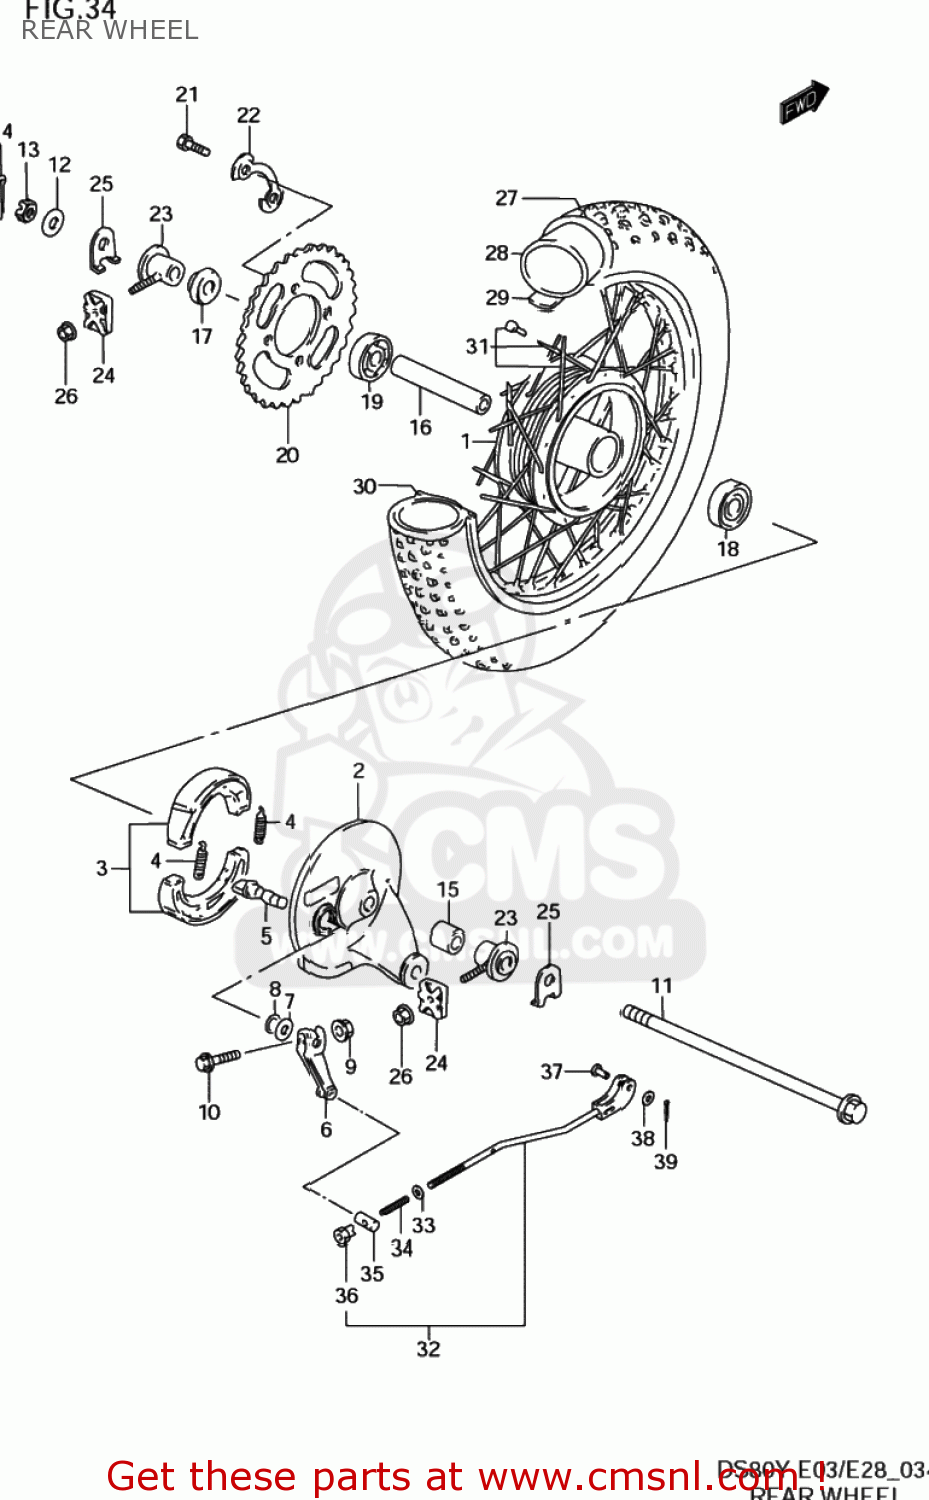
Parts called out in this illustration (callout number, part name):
1	HUB,RR
2	PANEL,RR BRAKE ANCHOR
3	SHOE SET,BRAKE (NAS)
4	SPRING(L:35.8)
5	CAM,BRAKE
6	LEVER,RR BRAKE CAM
7	WASHER(14.5X22X1.6)
8	O RING(D:2.5,ID:13.8)
9	NUT
10	BOLT
11	AXLE,RR
12	WASHER
13	NUT,M12X1.25X1
14	COTTER PIN
15	SPACER(12.1X22X22)
16	SPACER(12.6X19X91)
17	SPACER,RR AXLE,L
18	BEARING
19	BEARING
20	SPROCKET,RR(NT:34)
21	BOLT(8X25)
22	WASHER
23	ADJUSTER,CHAIN
24	PLATE,CHAIN ADJUSTER GUIDE
25	WASHER,CHAIN ADJUSTER
26	NUT
27	TIRE(3.00 12)
28	TUBE,INNER
29	PROTECTOR,INNER TUBE
30	RIM,RR WHEEL(1.60X12)
31	SPOKE ASSY,RR WHEEL
32	ROD ASSY,RR BRAKE
33	WASHER
34	SPRING
35	PIN(11X18)
36	NUT
37	PIN(L:13.5)
38	WASHER
39	PIN 20X20
